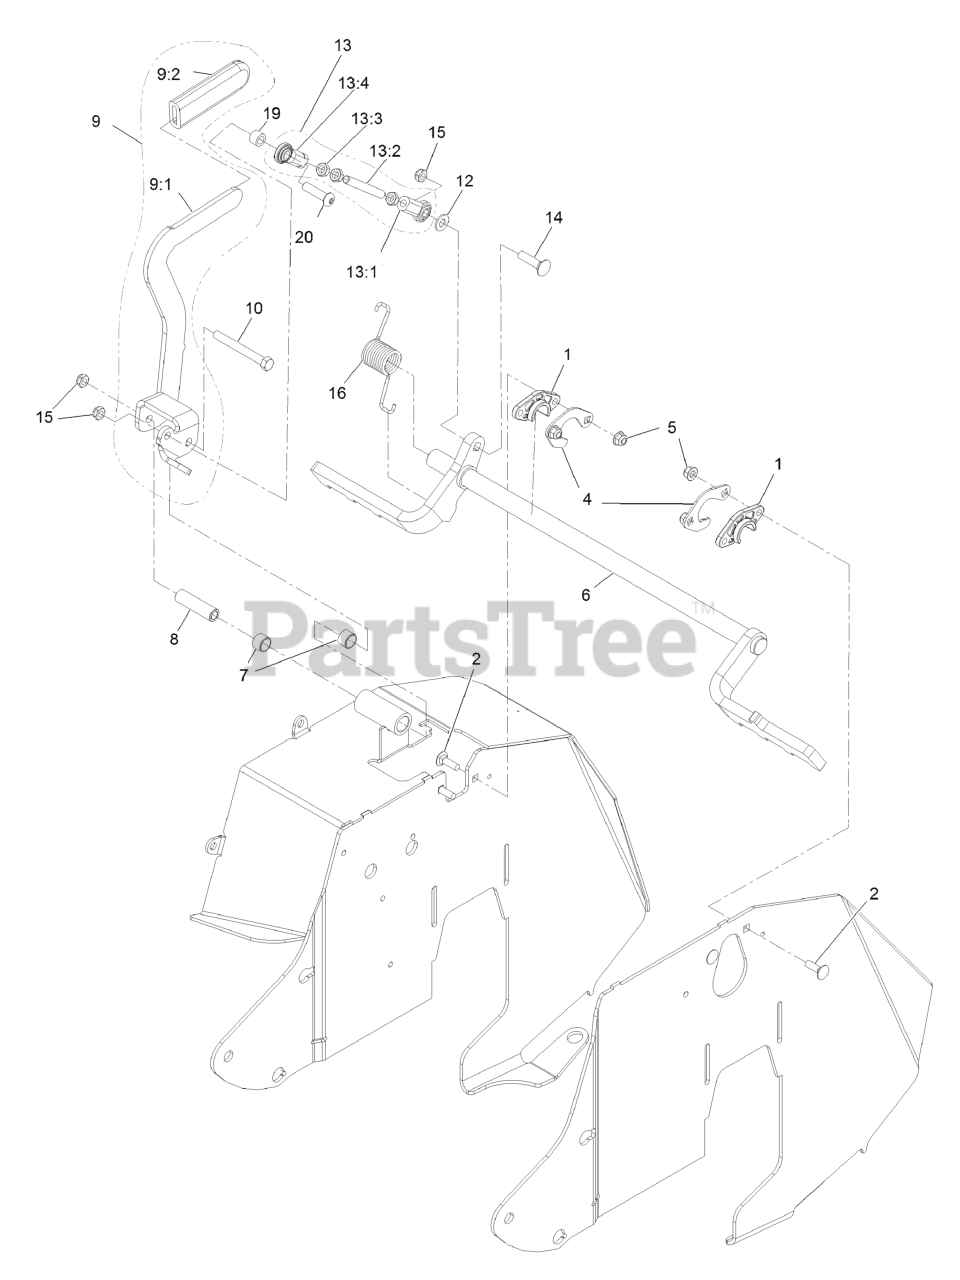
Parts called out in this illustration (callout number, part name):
1	BUSHING-FLANGE
2	BOLT-CARR
4	SUPPORT, BEARING
5	NUT-HF, NI
6	WLD-BRAKE SHAFT 32/36
7	SLEEVE-BUSHING
8	SPACER, BRAKE PIVOT
9	ASM, LEVER W/ GRIP
9:2	GRIP-LEVER
10	SCREW-HH
12	WASHER-FLAT
13	ASM, BRAKE LINK
13:1	JOINT-BALL, END
13:2	LINKAGE, BRAKE
13:3	NUT-HJ
13:4	JOINT-BALL END, LH
14	SCREW-CARR
16	SPRING-TORSION
20	Screw-HSBH
